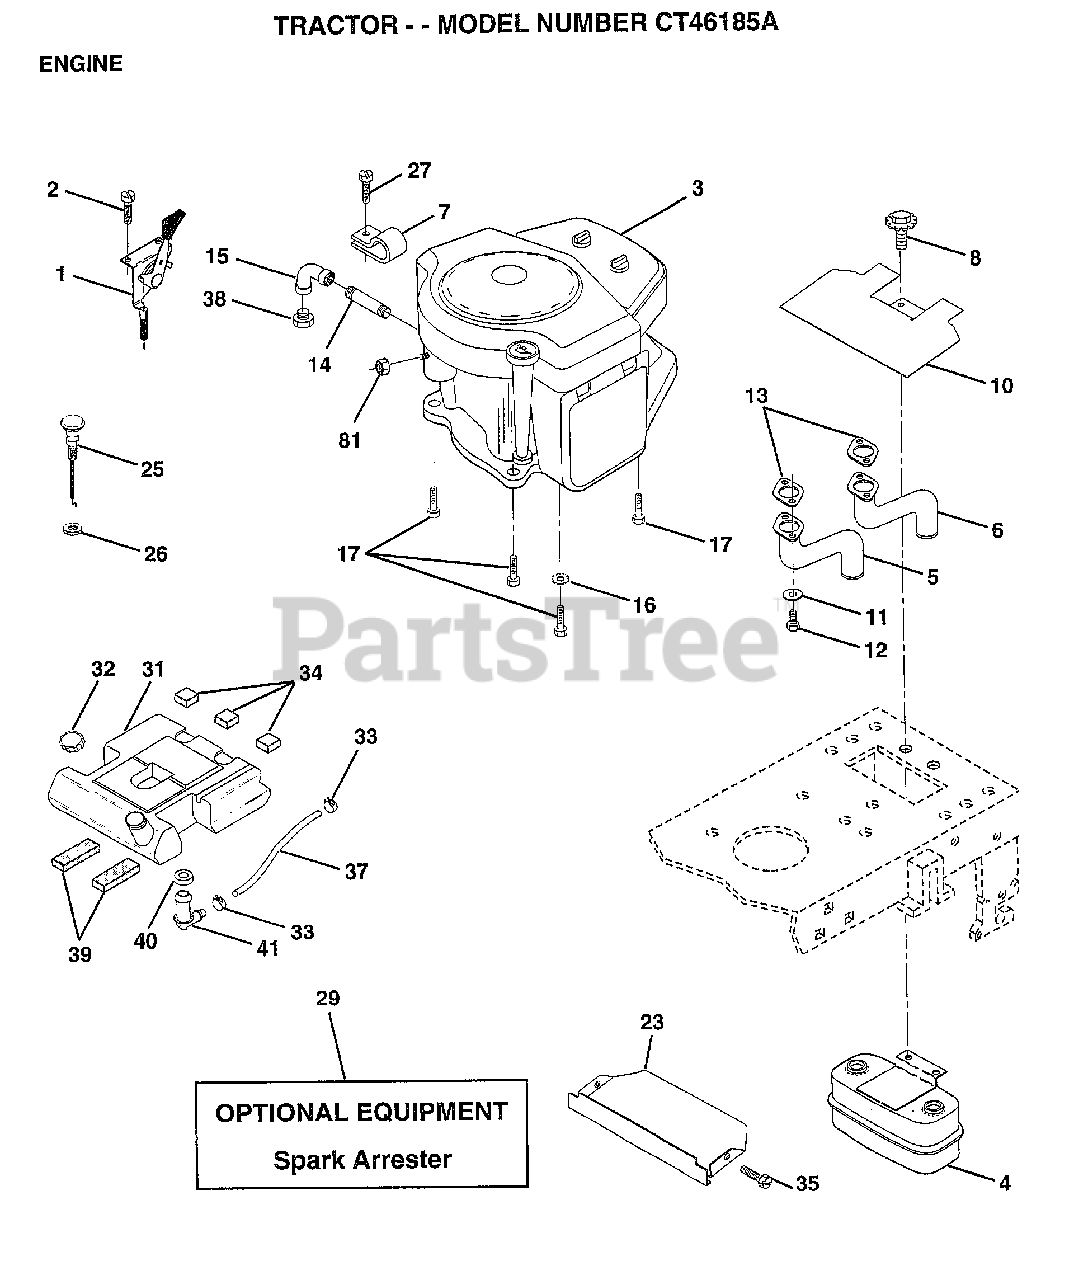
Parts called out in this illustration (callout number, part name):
1	CONTROL.TRTL.37
2	SCREW LT
4	MUFFLER.TW.LOTONE
5	EXHAUST.B&S.18.LH
6	EXHAUST.B&S.18.RH
7	CLAMP.TUBE.DBL.EN
8	BOLT.5/16-18.UNC
10	SHIELD.HEAT.
11	LOCKWASHER
13	GASKET MUFFLER
14	PIPE NIPPLE LT
15	ELBOW
16	LOCKWASHER
17	SCREW LT
23	SHIELD.BRN/DBR.GD
25	"CONTROL.CHOKE.51"""
26	"NUT,KEPS 3/8-24IM"
27	"SCREW-TT,10-32 FL"
31	TANK FUEL REAR
32	CAP ASM FUEL
33	HOSE CLAMP
34	PAD-SPACER LT
35	SCREW
37	FUEL LINE T
39	PAD IDLER TI
40	BUSHING OUTLET T
41	STEM.TANK.FUEL
81	NUT
